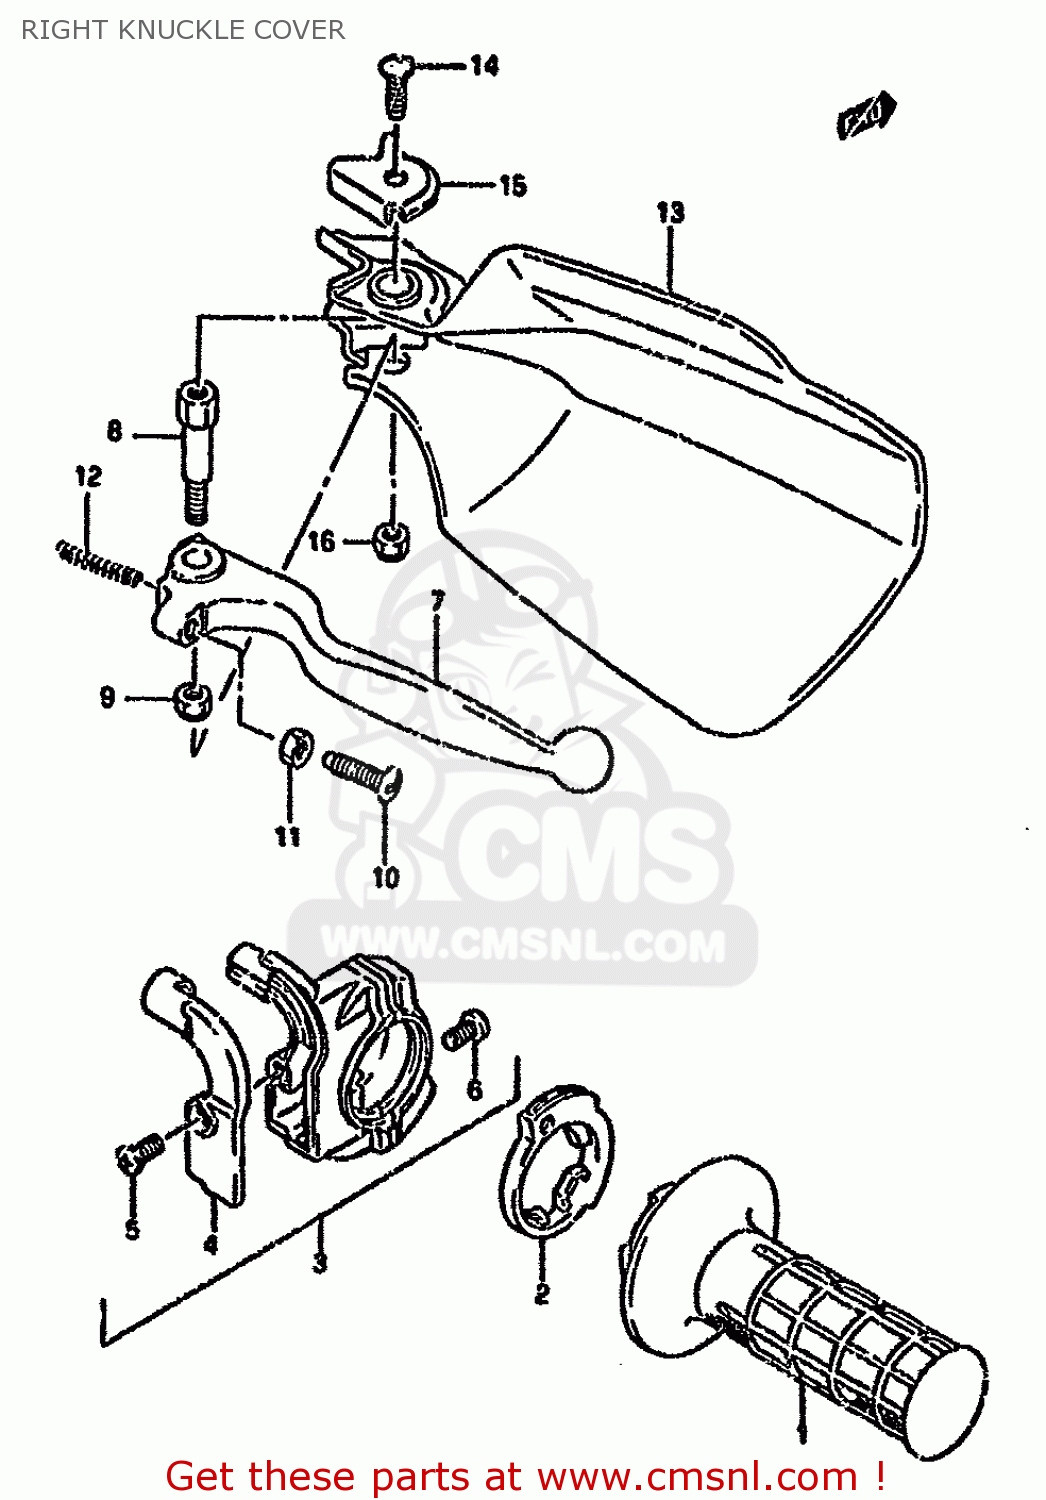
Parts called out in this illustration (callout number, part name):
1	GRIP,THROTTLE
2	ROTOR,THROTTLE GRIP
3	CASE ASSY,THROTTLE
4	COVER,THROTTLE CASE
5	SCREW 4X10
6	SCREW
7	LEVER,BRAKE
8	BOLT,BRAKE LEVER PIVOT
9	NUT 6MM
10	BOLT,ADJUST
11	NUT ,5MM
12	SPRING,RETURN
13	COVER,KNUCKLE,RIGHT
14	SCREW
15	PLATE,KNUCKLE COVER,R UPR
16	NUT 6MM
